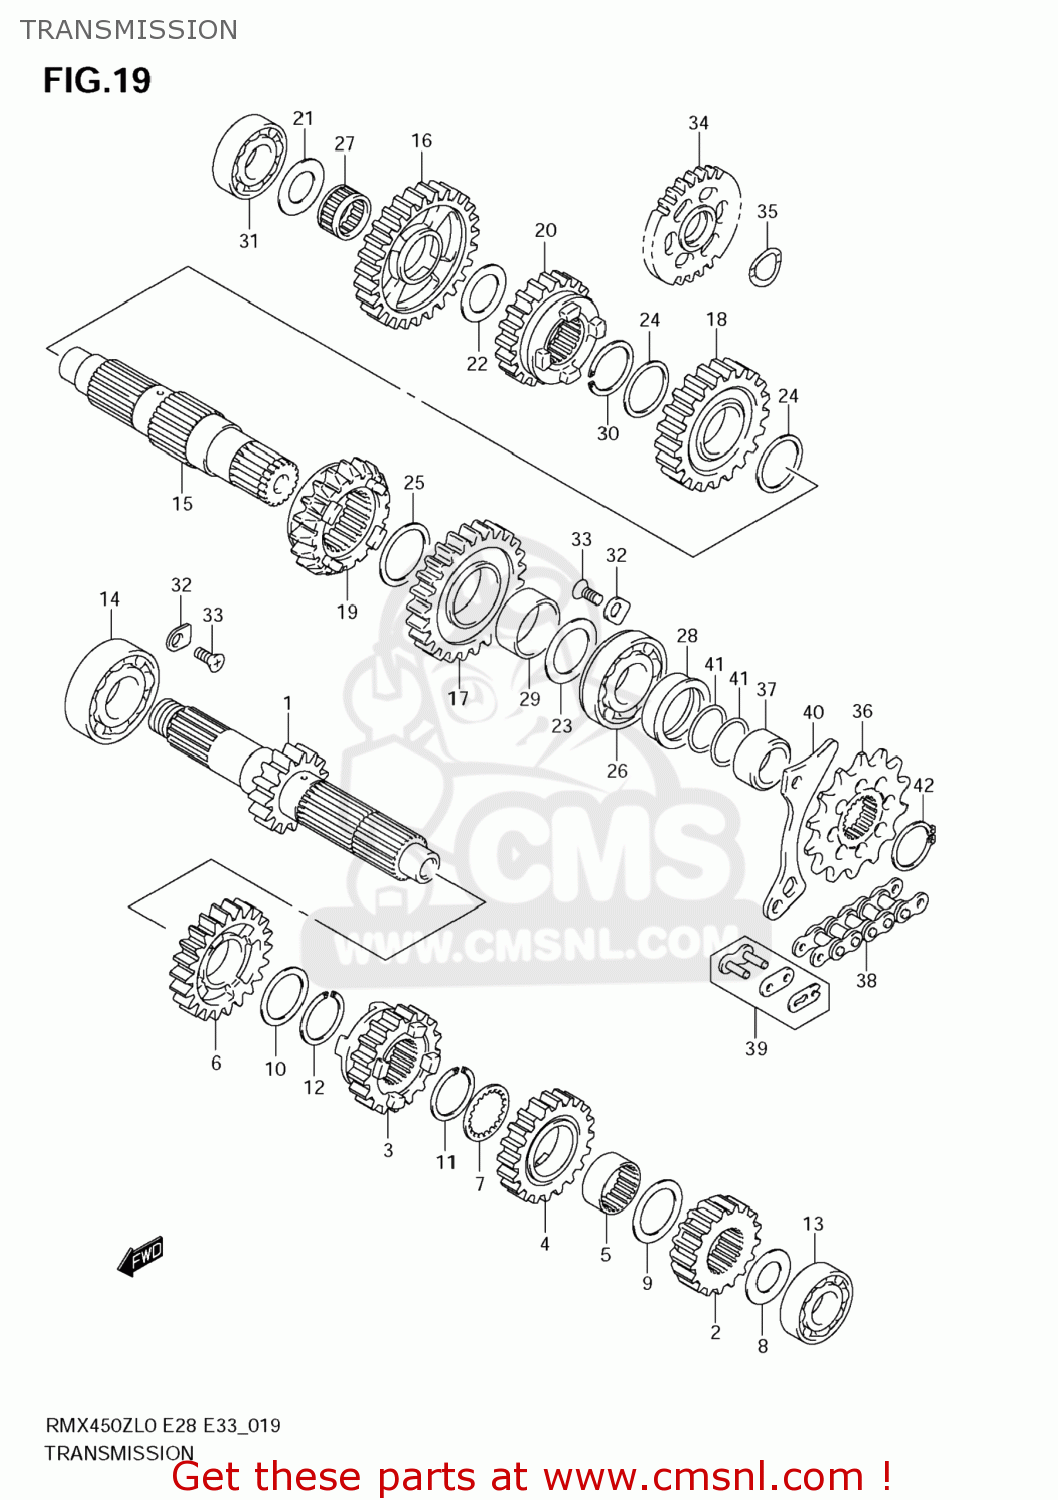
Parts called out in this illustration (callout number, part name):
1	SHAFT,COUNTER
2	GEAR,2ND DRIVE
3	GEAR,3RD DRIVE
4	GEAR,4TH DRIVE
5	BUSH,4TH DRIVE GEAR
6	GEAR,5TH DRIVE
7	WASHER,LOCK
8	SHIM(17X30X1)
9	SHIM(25X34X1)
10	SHIM(25X30X1)
11	CIRCLIP
12	CIRCLIP
13	BEARING
14	BEARING
15	SHAFT,DRIVE
16	GEAR,1ST DRIVEN
17	GEAR,2ND DRIVEN
18	GEAR,3RD DRIVEN
19	GEAR,4TH DRIVEN
20	GEAR,5TH DRIVEN
21	SHIM(17X30X1)
22	SHIM(20X30X1)
23	SHIM(24X34X1)
24	SHIM(25X30X1)
25	SHIM(27X33X1)
26	BEARING(24X56X14)
27	BEARING(20X24X10)
28	SEAL,OIL(31X40X6.7)
29	BUSH(27X31X13)
30	CIRCLIP
31	BEARING
32	RETAINER,COUNTER BEARING,R
33	SCREW(6X12)
34	GEAR,KICK STARTER IDLE
35	WASHER,KICK IDLE
36	SPROCKET,ENGINE(NT:13)
37	SPACER,ENGINE SPROCKET
38	CHAIN,DRIVE
39	JOINT SET,CHAIN
40	PLATE,FR CHAIN GUIDE
41	O RING(D:1.9,ID:21.8)
42	CIRCLIP
